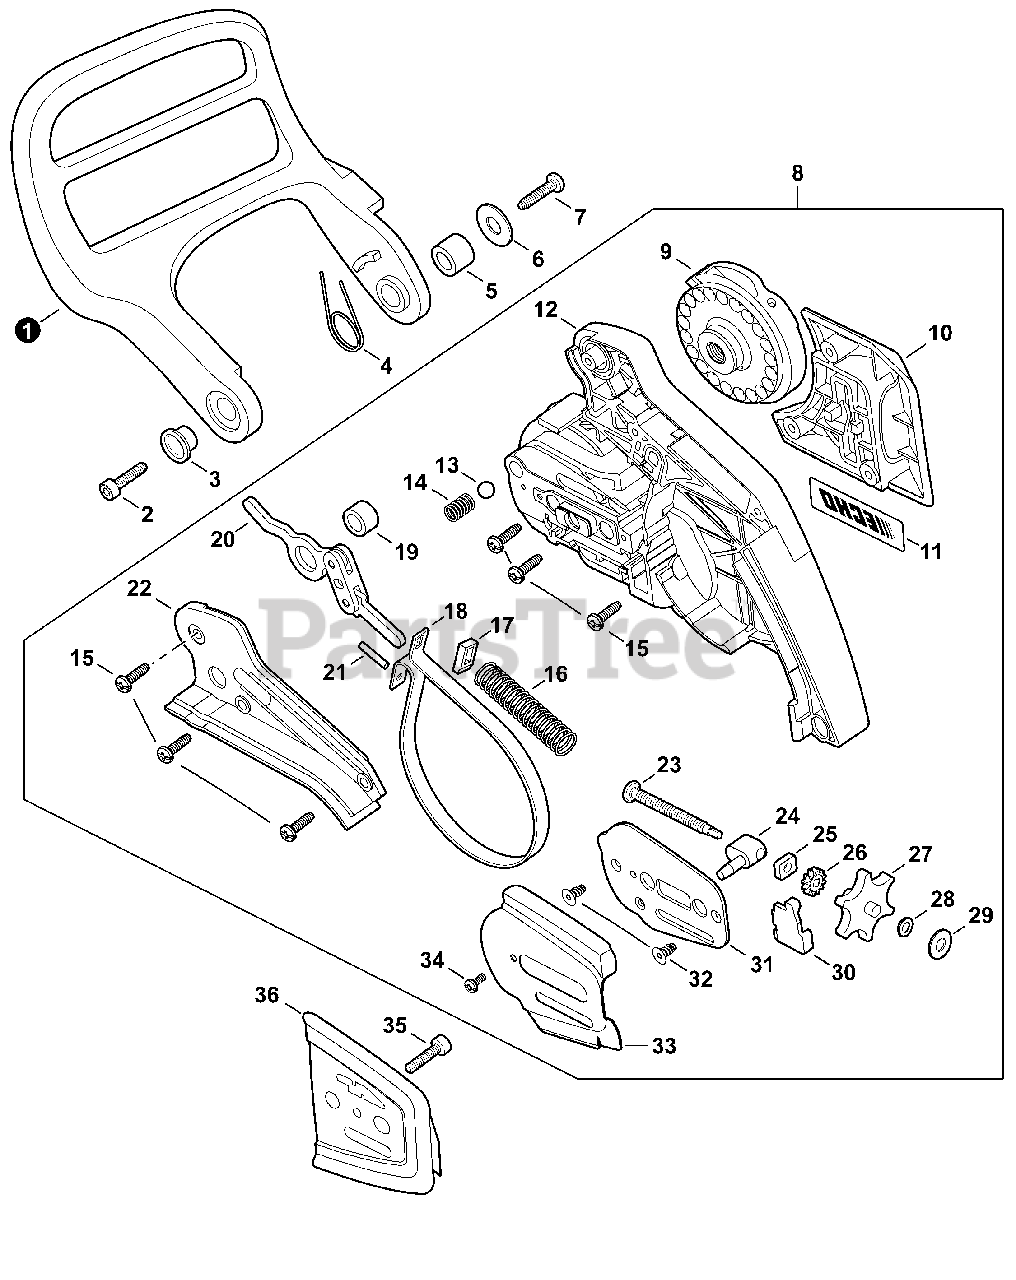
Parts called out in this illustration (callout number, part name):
1	LEVER, BRAKE
2	BOLT 5×16
3	COLLAR 10
4	SPRING, TORSION
5	SPACER 8×12×9
6	WASHER 4.2×16.5×1
8	CHAIN TENSIONING ASSY, TOOL-LESS
9	KNOB, SPROCKET GUARD
10	WHEEL COVER
11	LABEL, ECHO
12	GUARD, SPROCKET
14	SPRING, COMPRESSION
15	SCREW 4×12
16	SPRING, COMPRESSION
18	BAND, BRAKE
19	SPACER 8×12×9
20	CONNECTOR, BRAKE
21	PIN, SPRING 3x-9.8
22	COVER, BRAKE
23	SCREW, CHAIN TENSIONER
24	TENSIONER, CHAIN
25	COLLAR 4
26	GEAR, SPUR
27	WHEEL, TENSION
28	WASHER, WAVE
29	WASHER 5
30	COVER, GEAR
31	PLATE, EYE
32	SCREW 3
33	PLATE, GUIDE - OUTER
34	SCREW 3×6
35	SCREW 4×12
36	PLATE, GUIDE - INNER
